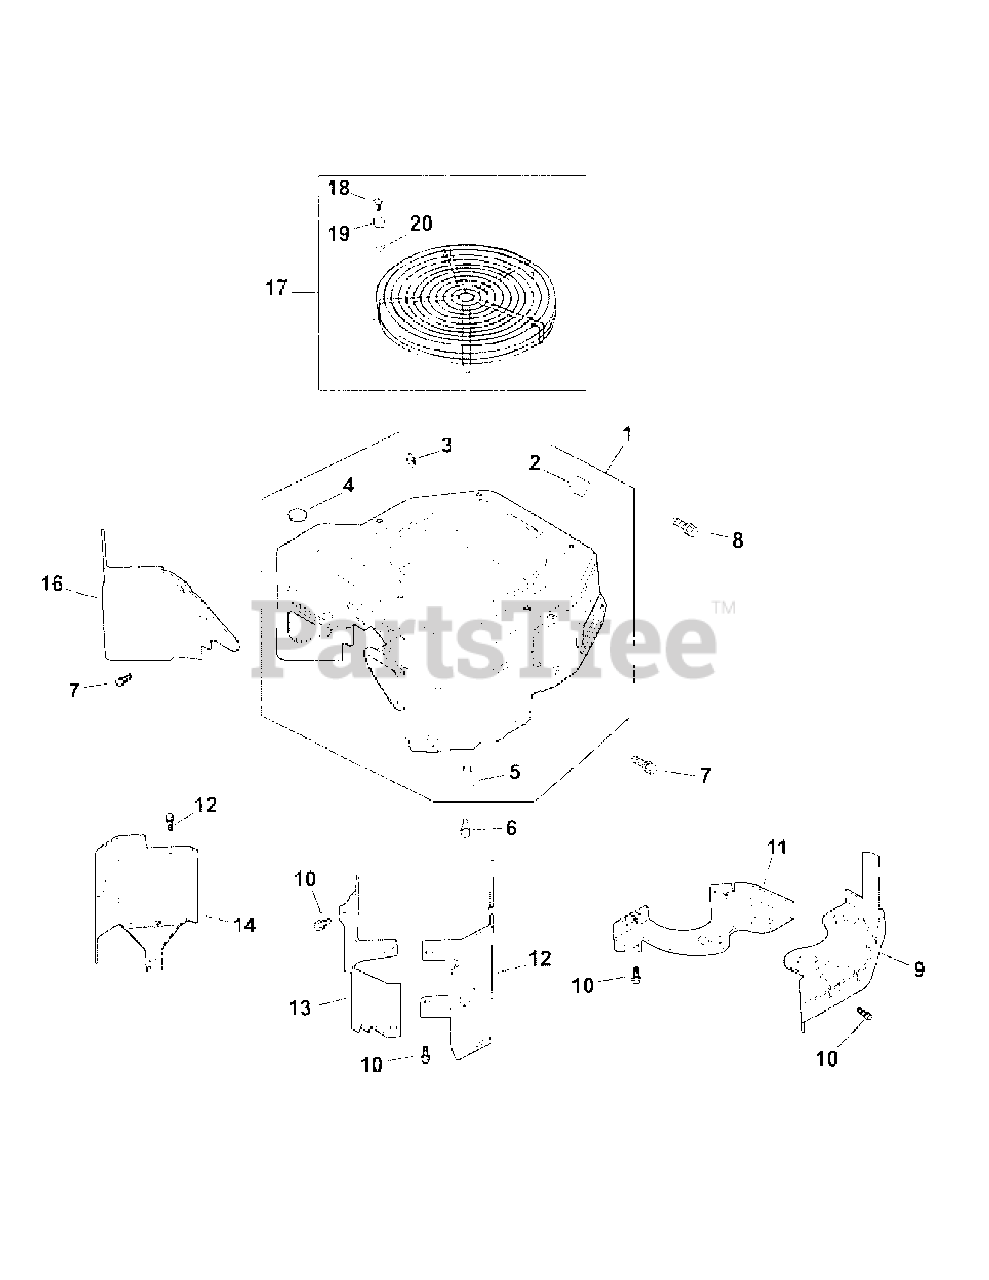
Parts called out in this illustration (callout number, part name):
1	Blower Housing
6	Hex Flange Screw
7	Hex Flange Screw
8	Hex Flange Screw
9	Backing Plate
10	Hex Flange Screw
11	Backing Plate
12	Cylinder Barrel Baffle
13	Valley Baffle
14	Cylinder Barrel Baffle
15	Hex Flange Screw
16	Valley Baffle
18	Pan Head Screw
19	Spacer
